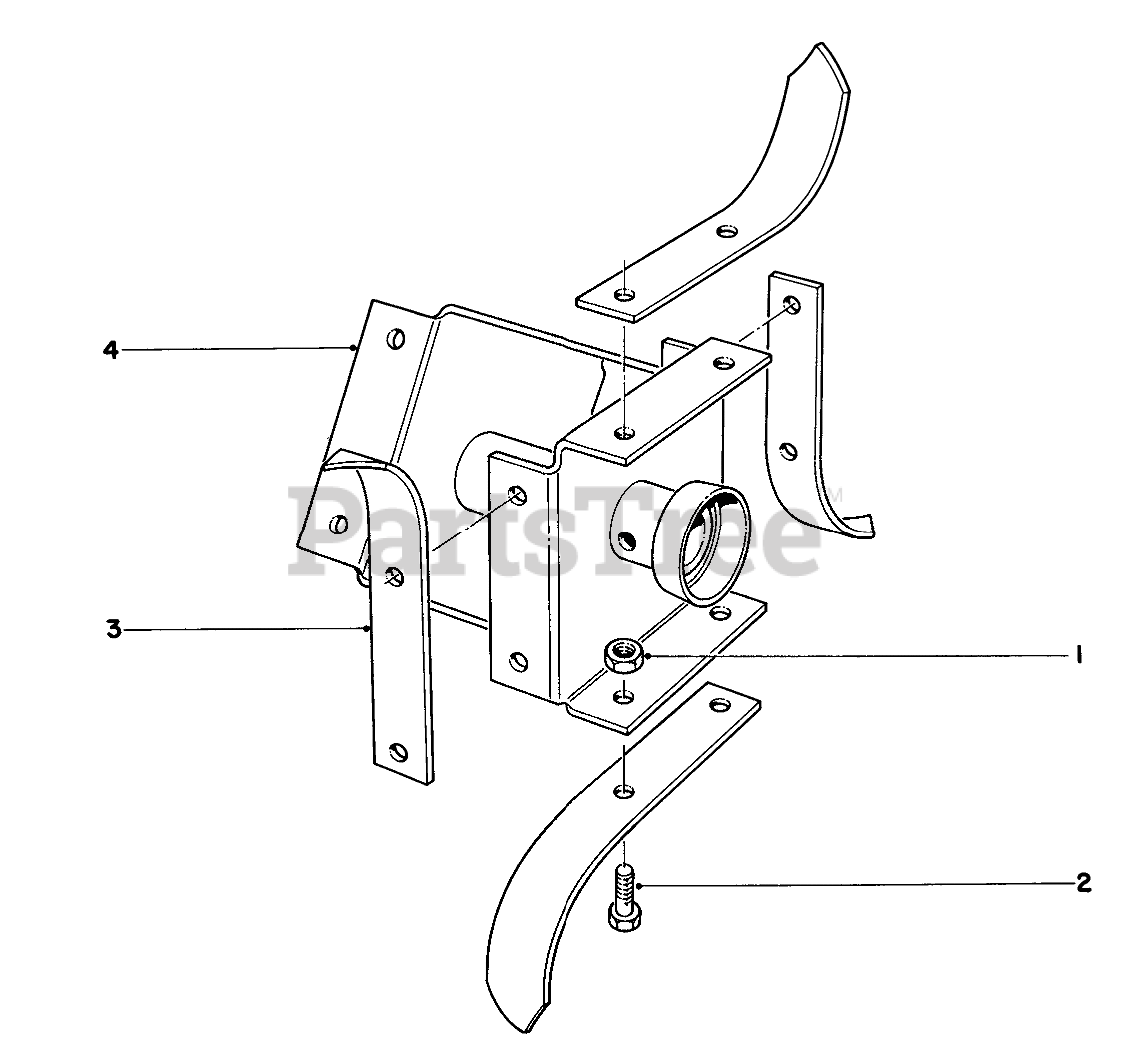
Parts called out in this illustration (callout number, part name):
1	NUT-LOCK, CONE
2	Capscrew
3	Pick Tine
4	Axle Welded R.H.
